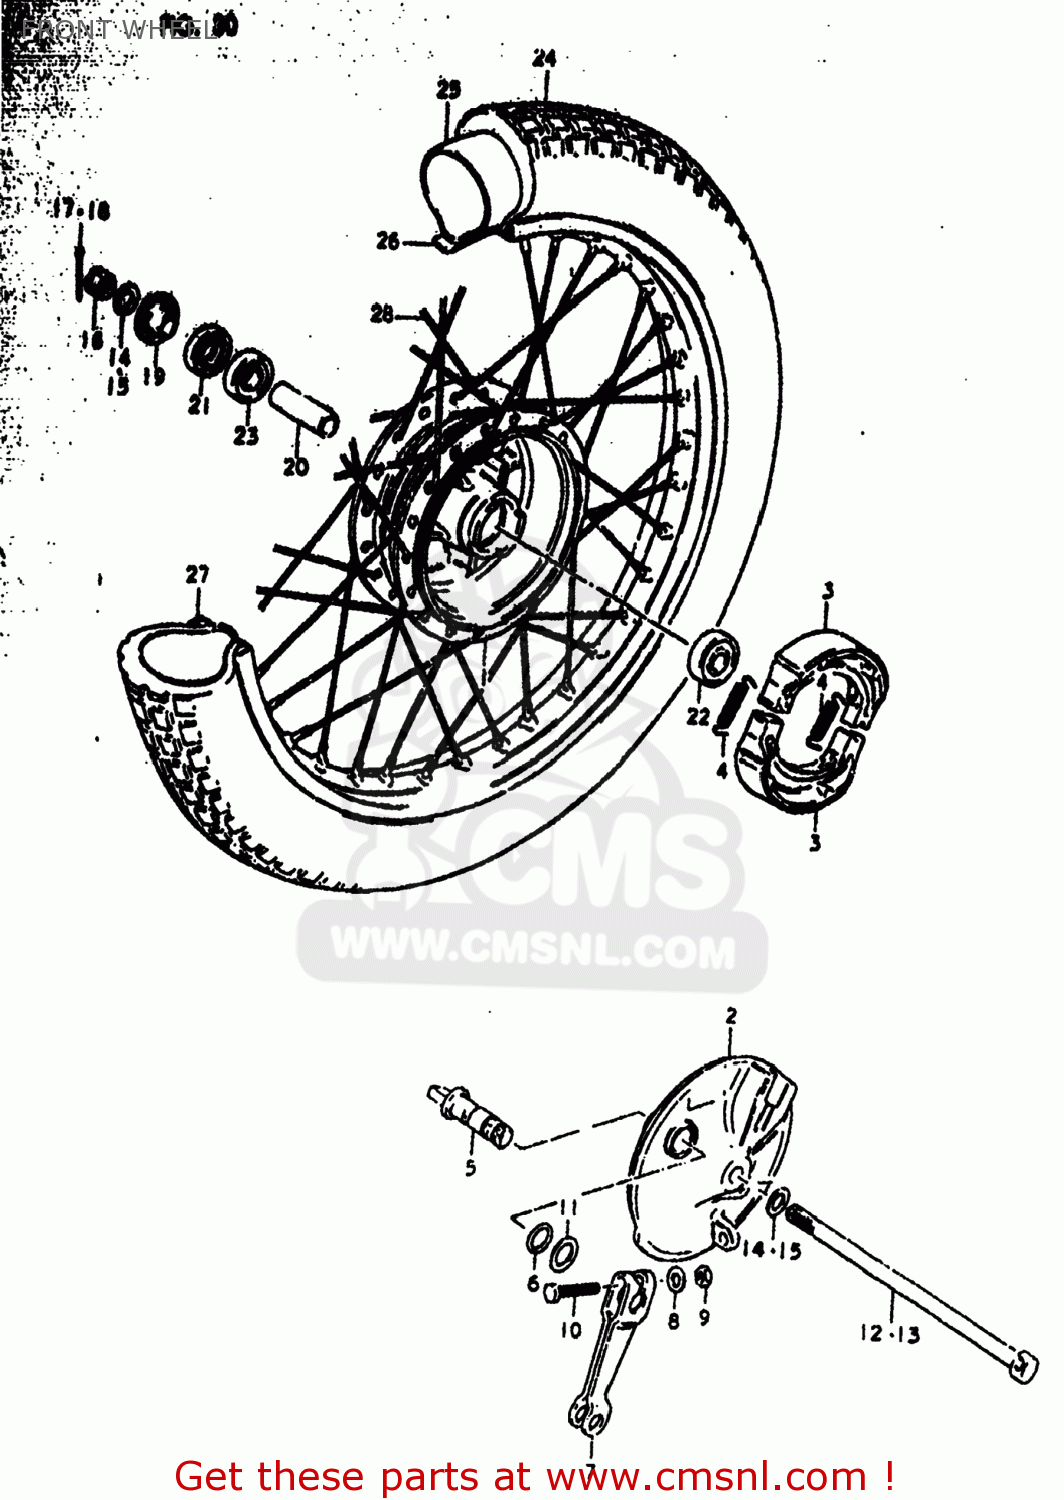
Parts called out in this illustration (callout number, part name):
1	HUB,FRONT
2	PANEL,FRONT HUB
3	SHOE,BRAKE
4	SPRING(L:34)
5	CAM,FR BRAKE
6	O RING(D:2.5,ID:11.4)
7	LEVER,FR BRAKE CAM
8	WASHER
9	NUT
10	BOLT
11	WASHER(12.5X20X1)
12	AXLE,FRONT
13	AXLE,FRONT
14	WASHER
15	WASHER(10.5X22X2.3)
16	NUT
17	COTTER PIN
18	PIN 20X20
19	SPACER,FRONT AXLE,RIGHT
20	SPACER (10.2X16X51)
21	SEAL,OIL(15X31X5)
22	BEARING
23	BEARING
24	TIRE,FRONT
25	TUBE,INNER
26	PROTECTOR,INNER TUBE
27	RIM,FRONT WHEEL (1.40X14)
28	SPOKE SET,FRONT
